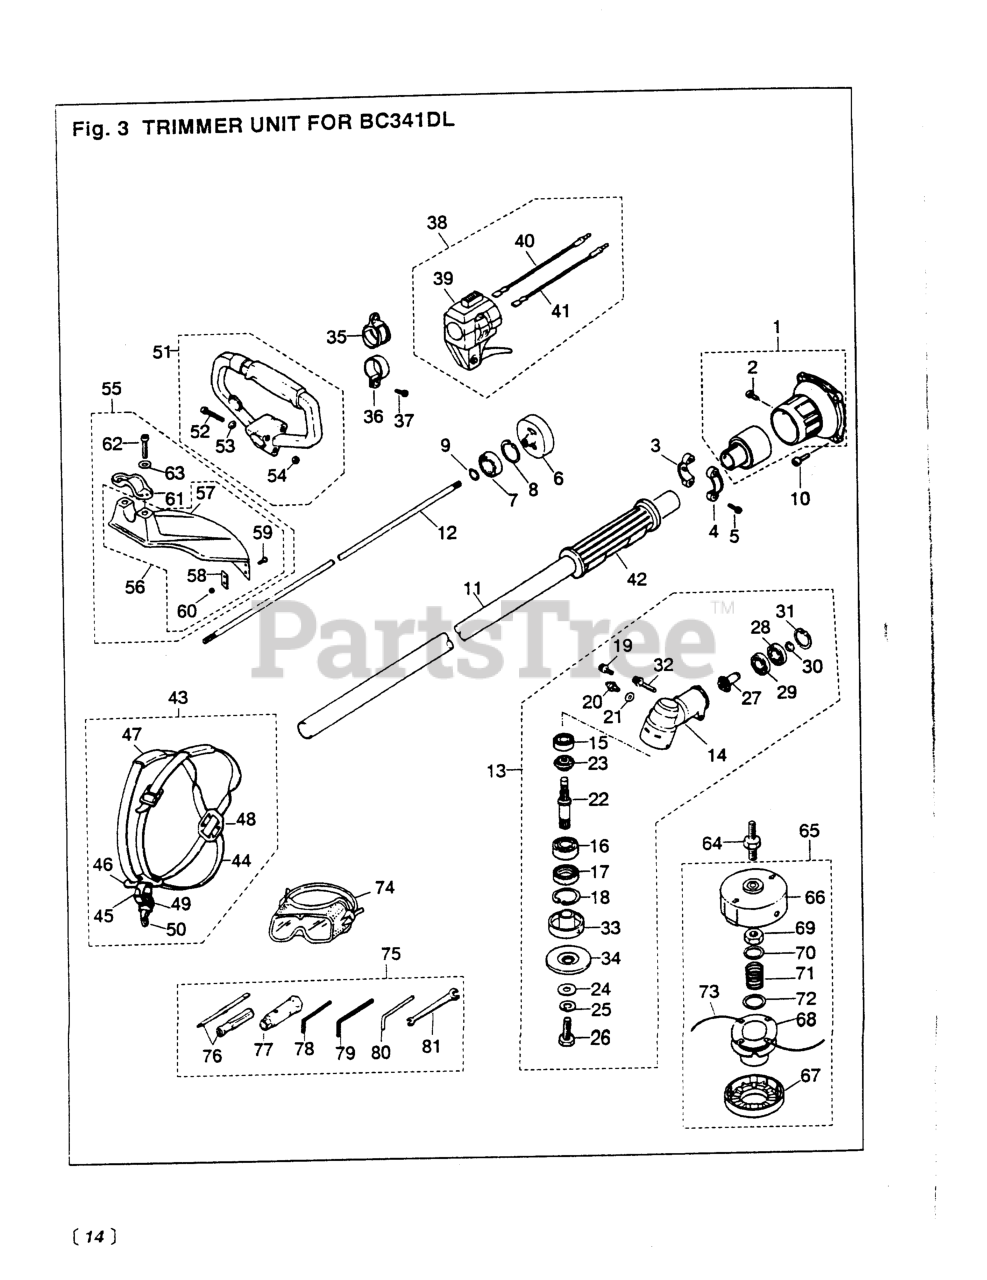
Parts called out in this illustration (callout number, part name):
2	SCREW, M6 x 10
5	BOLT
6	DRUM, CLUTCH
7	BEARING
8	RING, SNAP, M35 X 1.5
9	RING, SNAP, M15 X 1.0
12	SHAFT, SPLINE
15	BEARING (RPLS T3403-13510)
17	SEAL, OIL
18	RING, SNAP, M32 x 1.2
19	BOLT, M5 X 10
20	FITTING, GREASE
21	WASHER, M6 X .8
22	SHAFT, GEAR
23	GEAR, BEVEL
24	WASHER, M8 x 2.3 (RPLS -20823)
25	WASHER (RPLS 3180-13270)
26	BOLT, LH
29	BEARING (RPLS T3403-13510)
30	RING, SNAP
32	BOLT, M6 x 1.35
33	HOLDER (A)
34	HOLDER (B)
35	HANGER
36	CLAMP
37	SCREW, M5 x 25
40	CORD-A, BLACK
41	CORD-B, RED
47	PROTECTOR
51	HANDLE ASSEMBLY
52	SCREW, M5 x 30(RPLS 0263-00530
53	WASHER, M5 x 10
54	NUT, M5 X 4
58	BLADE
59	SCREW, M5 x 12
60	NUT
61	CLAMP
62	BOLT, M6 x 1.30
63	WASHER, M6 X 15
64	ARBOR, 8MM
65	6
67	COVER
69	NUT (NO LONGER AVAILABLE)
70	PLATE, LARGE
72	PLATE, SMALL
75	TOOL SET
76	SCREWDRIVER
78	WRENCH (TOOL)
79	WRENCH (TOOL)
80	BAR
81	SPANNER, 8 X 10 (RPLS 2540- )
